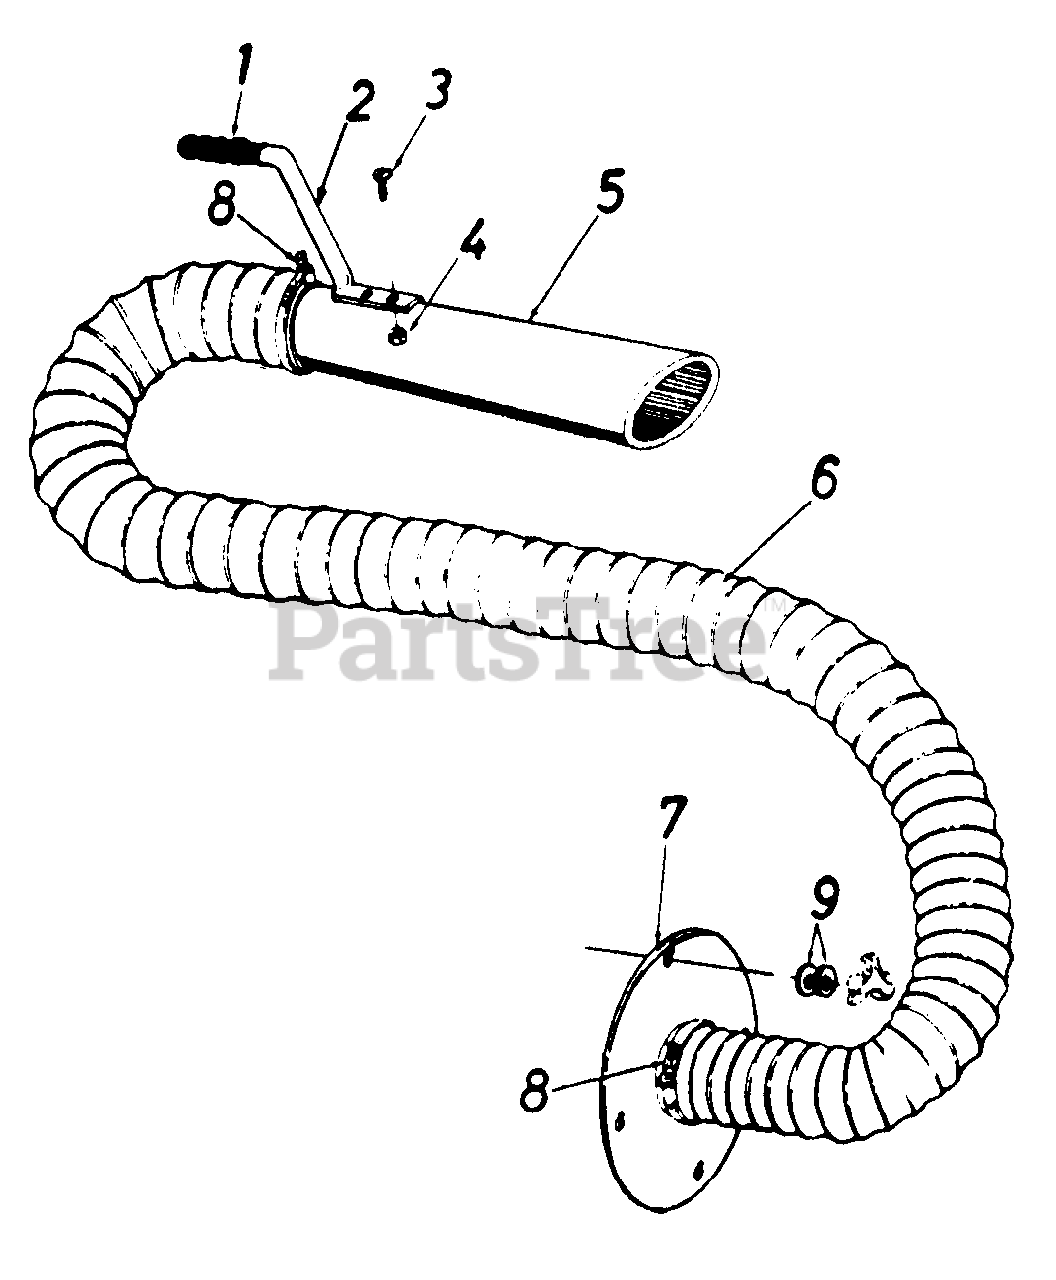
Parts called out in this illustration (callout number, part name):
1	Handle Grip
2	Handle
3	Truss Sems Scr.10-24 x 1/2" Lg.
4	Hex Nut 10-24 Thd.
5	Hose Nozzle
6	Flexible Hose 4" Dia. x 10' Lg.
9	Flat Washer .34 I.D. x 1.12 O.D.
